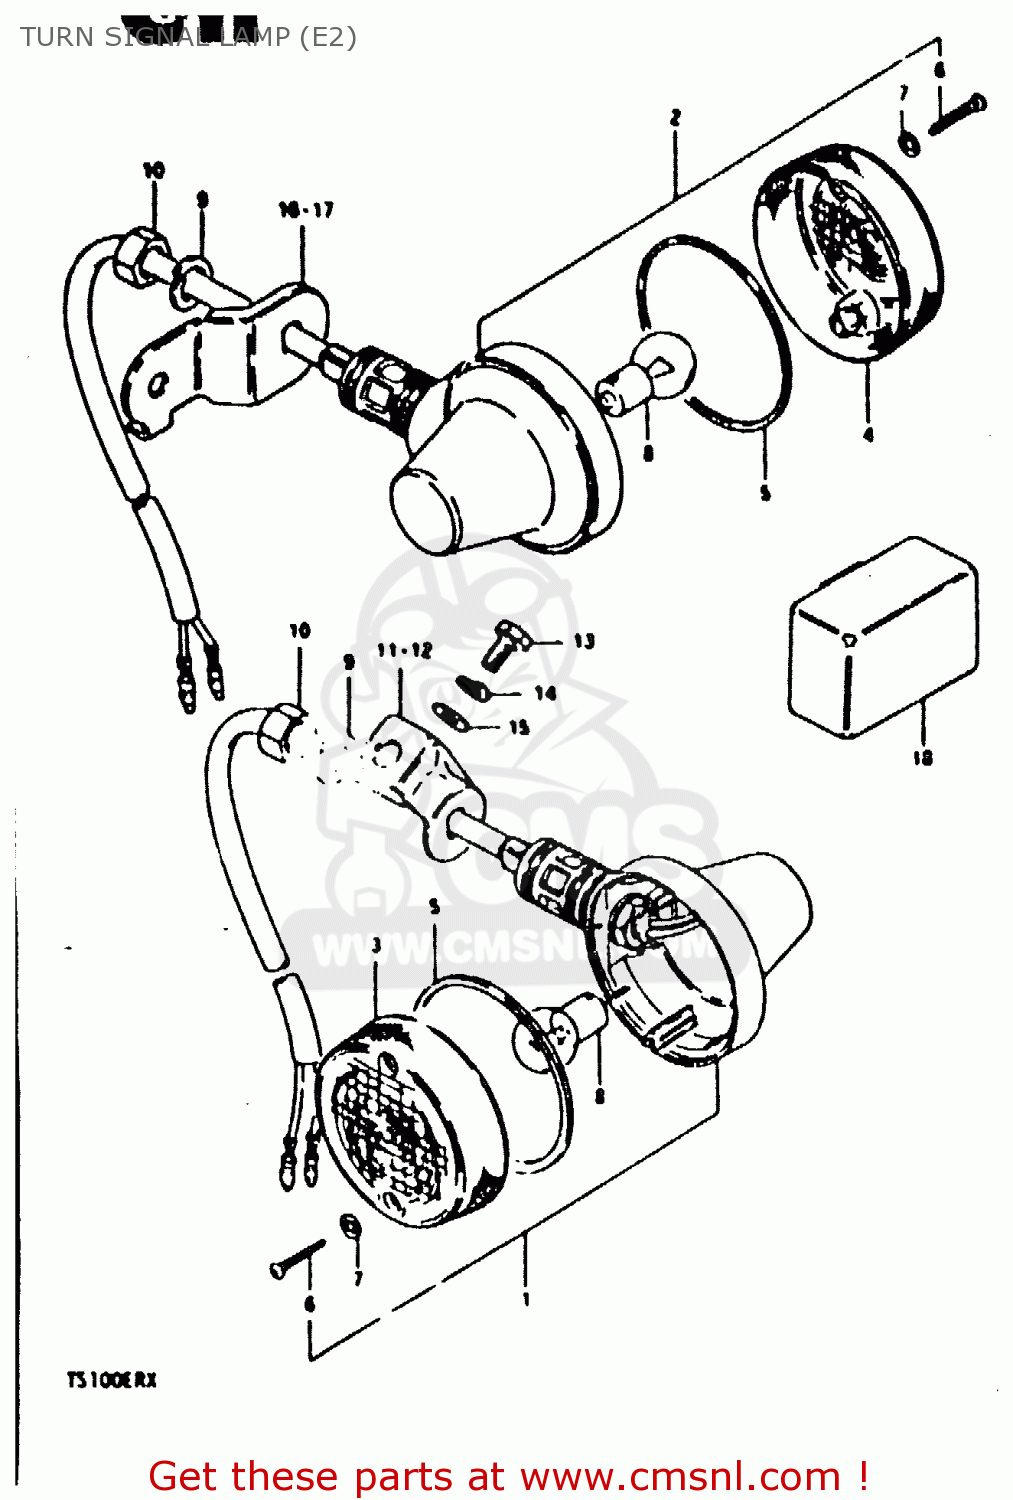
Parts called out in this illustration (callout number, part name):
1	LAMP ASSY,RR TURNSIGNAL
2	LAMP ASSY,RR TURNSIGNAL
3	LENS
4	LENS
5	GASKET (NAS)
6	SCREW TAPP.
7	GASKET (NAS)
8	BULB (6V,18W)
9	WASHER,LOCK 12
10	NUT
11	BRACKET,TURNSIGNAL LAMP,R
12	BRACKET,TURNSIGNAL LAMP,L
13	BOLT
14	LOCK WASHER
15	WASHER
16	BRACKET,REAR TURN SIGNAL
17	BRACKET,REAR TURN SIGNAL
18	RELAY,TURN SIGNAL
